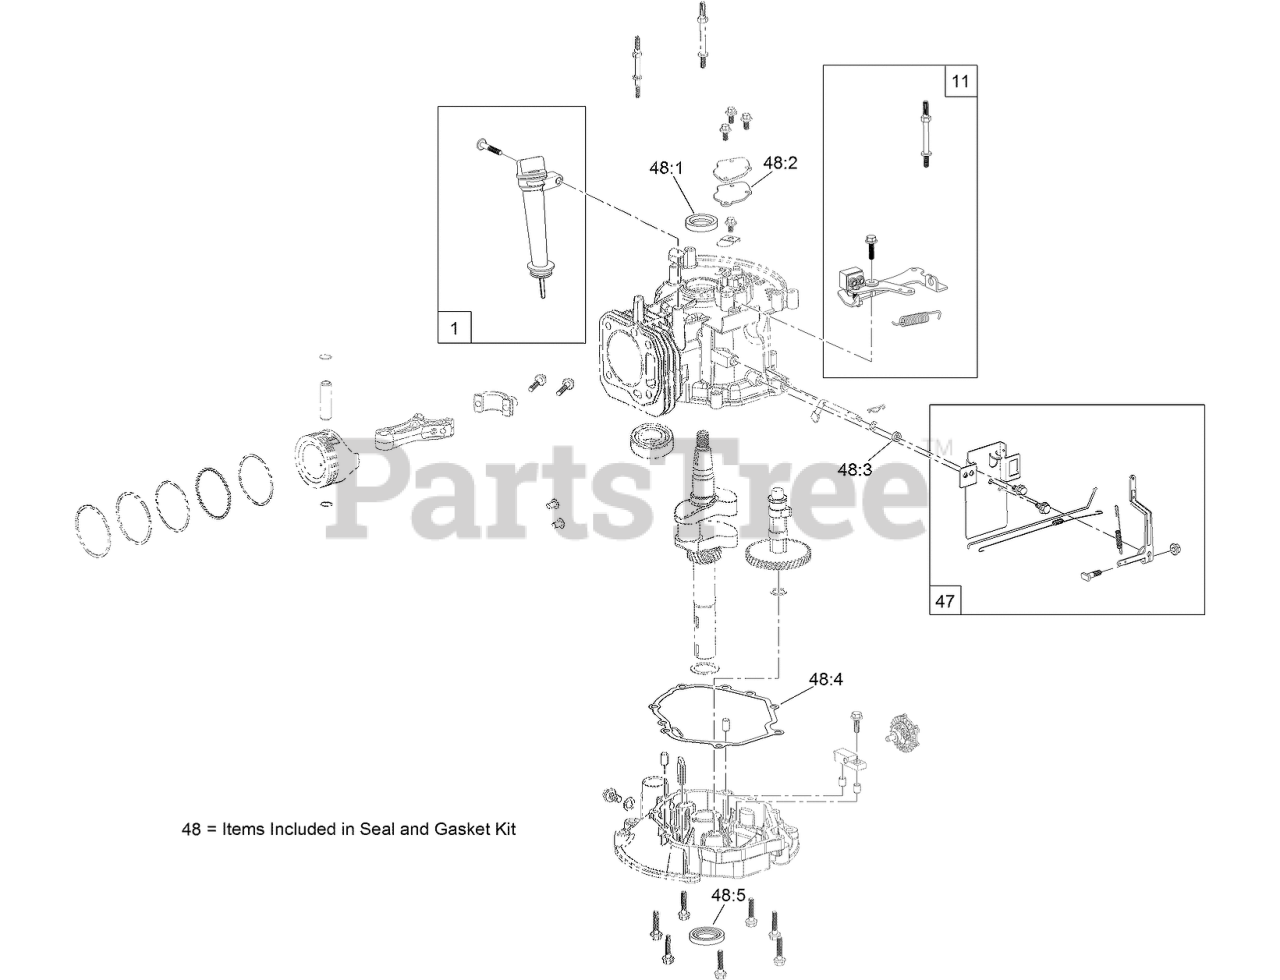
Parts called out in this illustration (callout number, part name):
1	DIPSTICK AND FILL TUBE KIT
11	BRAKE ASM RECOIL KIT
47	GOVERNOR ARM KIT
48	SEAL AND GASKET KIT
48:1	SEAL-OIL
48:2	GASKET-BREATHER
48:3	SEAL-OIL
48:4	GASKET-COVER, CASE
48:5	SEAL-OIL
